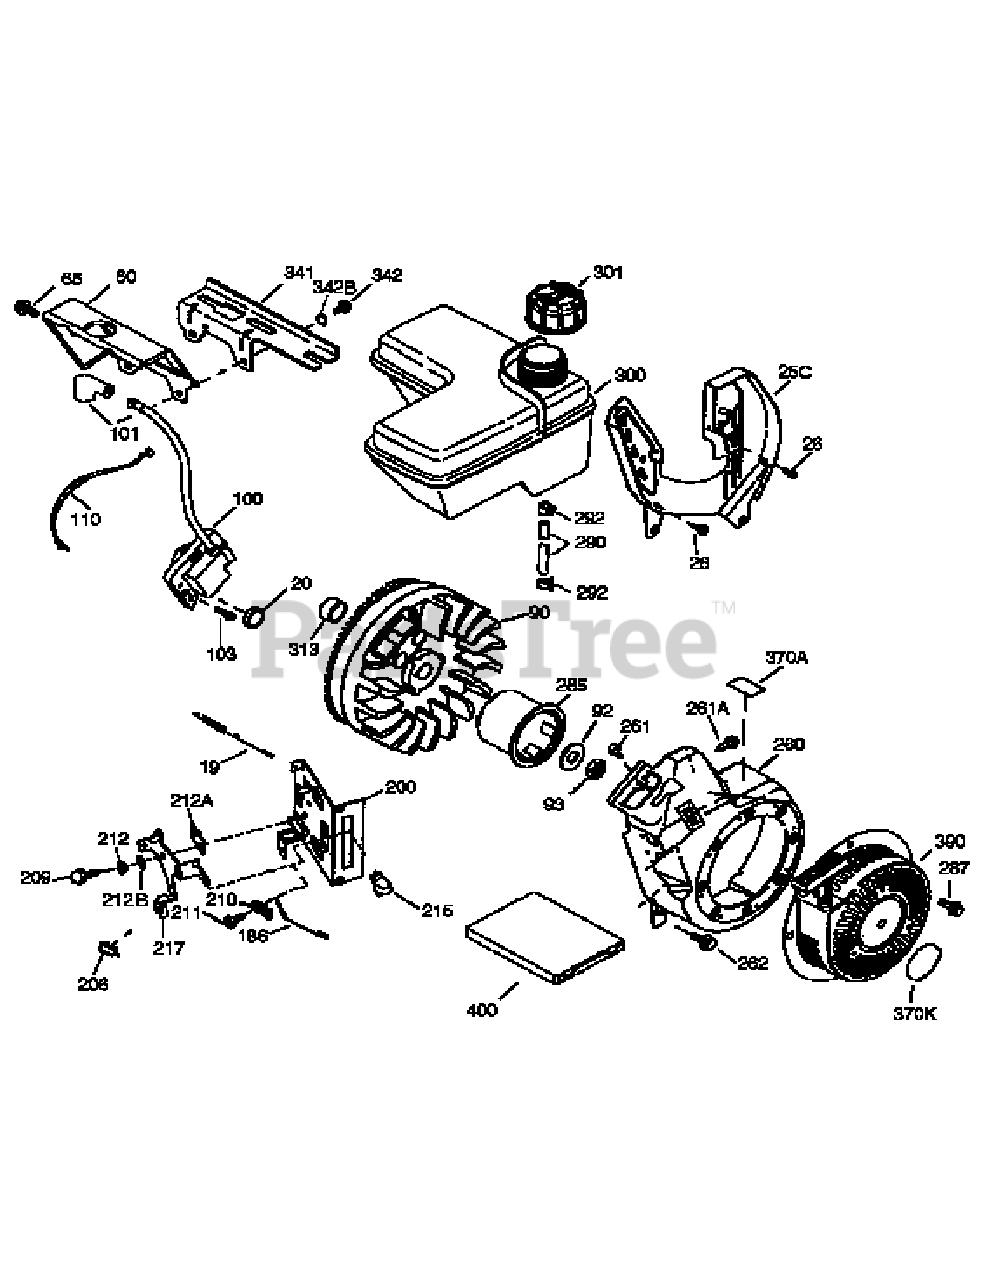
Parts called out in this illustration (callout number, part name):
19	Extension Spring
25C	Air Baffle
26	Screw, (10-24 x 9/16")
60	Blower Housing Extension
65	Screw, (10-24 x 9/16")
92	Bellville Washer
93	Flywheel Nut
100	Solid State Ignition
101	Spark Plug Cover
103	Screw, T-15, (10-24 x 15/16")
110	Ground Wire
186	Governor Link
200	Control Bracket
209	Screw, (10-32 x 1/2")
210	Conduit Clip
211	Screw, (10-32 x 3/8")
212A	Bearing Plate
215	Control Knob
217	Control Lever Assy.
260	Blower Housing
261	Screw, (1/4-20 x 31/64")
261A	Screw, (10-32 x 1/2")
262	Screw, (1/4-20 x 31/64")
285	Starter Cup
287	Screw, (1/4-20 x 31/64")
290	Fuel Line
292	Fuel Line Clamp
300	Fuel Tank
341	Fuel Tank Bracket
342	Screw, (1/4-20 x 19/32")
342B	Rubber Washer
370A	Instruction Decal
370K	Starter Decal
390	Rewind Starter
400	Gasket Set
